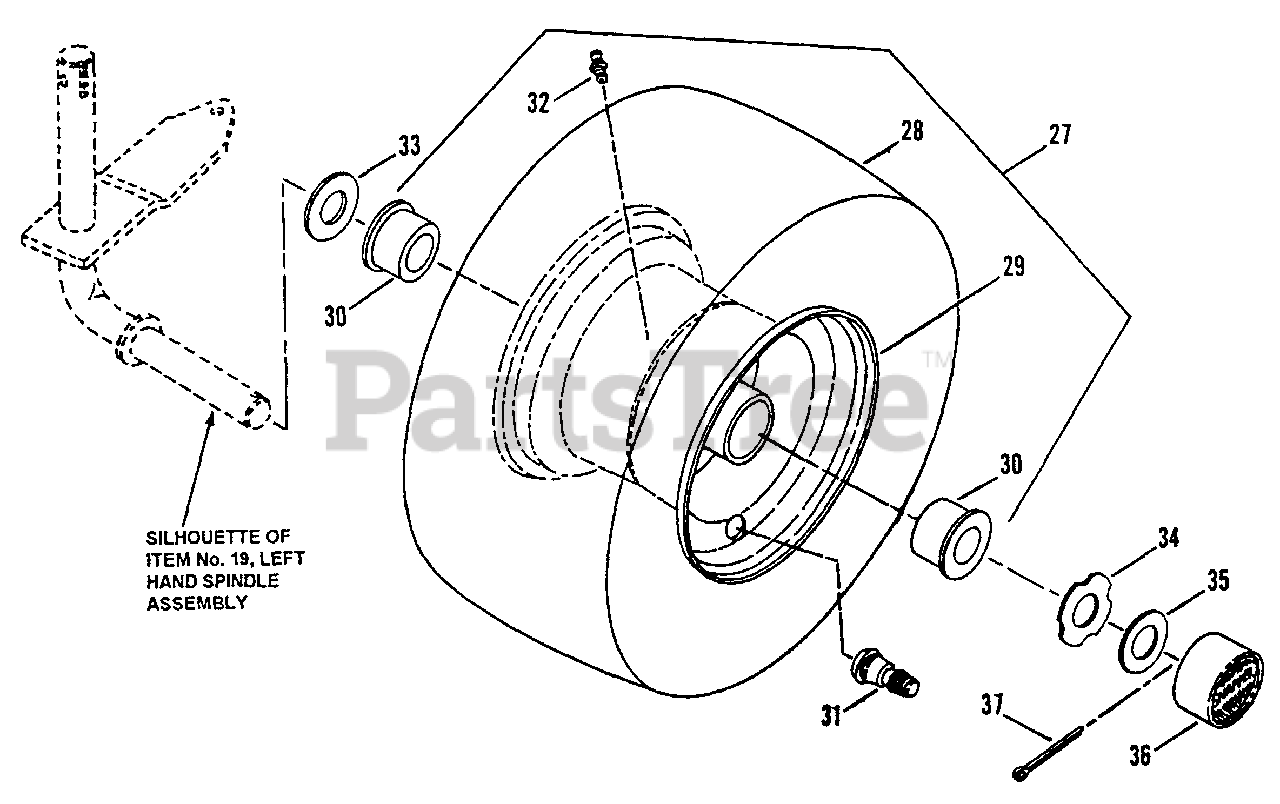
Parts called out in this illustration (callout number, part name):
27	ASSEMBLY, Front Tire & Rim, (30" & 33" Decks)
27	ASSEMBLY, Front Tire & Rim, (38" Decks)
28	TIRE, 13 x 5.00 (30" & 33" Decks)
28	TIRE, 15 x 6.00 (38" Decks)
29	RIM, 5.50 x 4.00
30	BEARING, Wheel
31	VALVE, Air (Snap-In)
32	FITTING, Lube 1/4-28 Tapered Thread
33	WASHER, 3/4" I.D
34	WASHER, Hub-Cap Retaining
35	WASHER, Flat, 49/64" I.D.
36	HUB-CAP
37	COTTER-PIN, 5/32 x 1"
